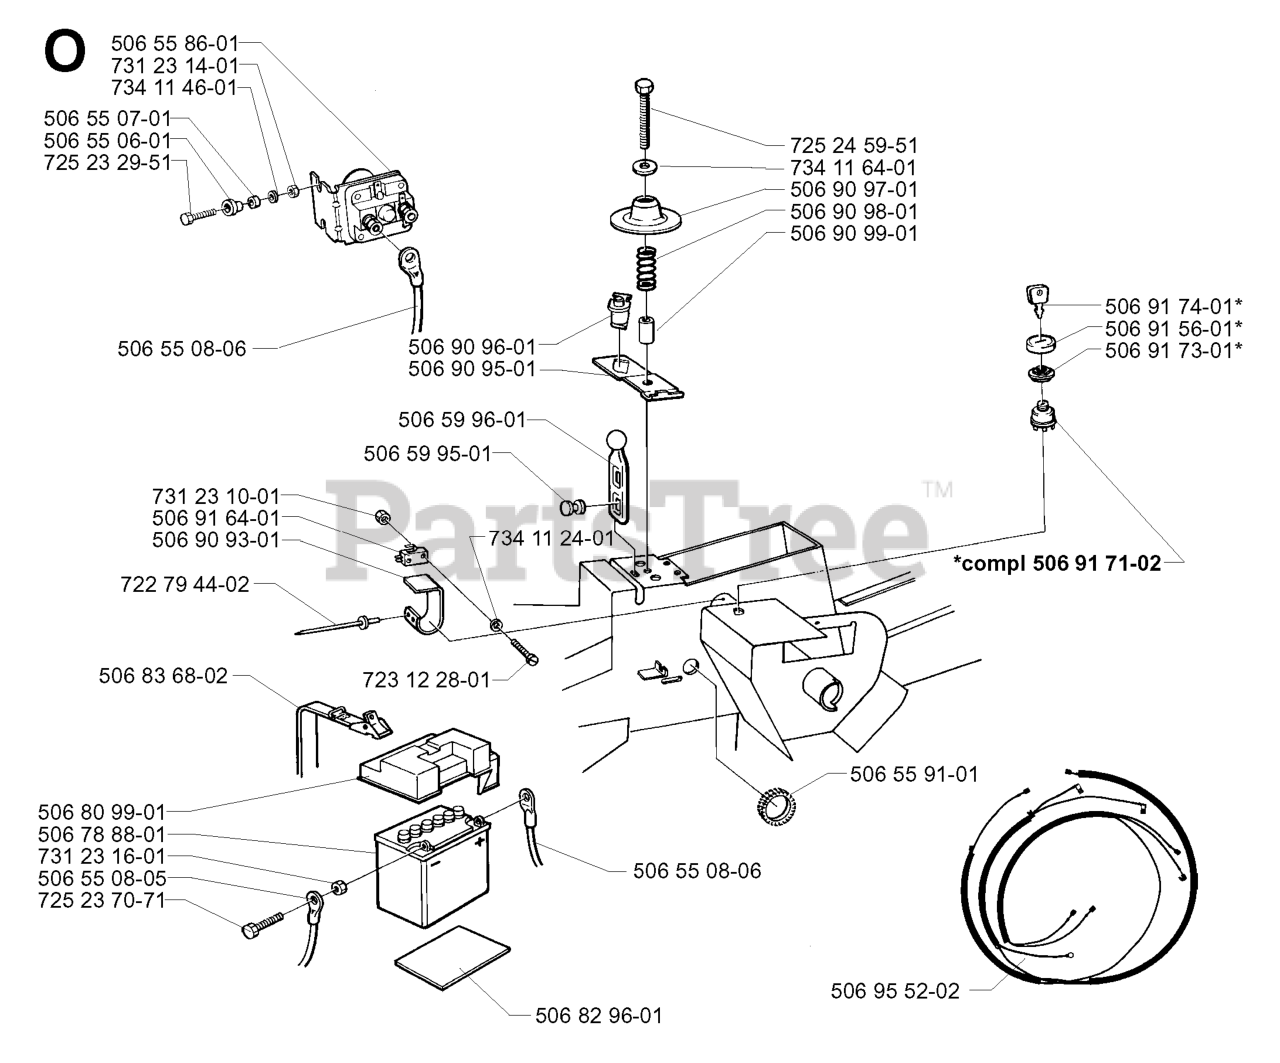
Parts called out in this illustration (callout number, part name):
1	DECK W/DECALS 61" HUS
2	SPINDLE ASSY - 52/61"
3	RP PULLEY - 61"
4	BLADE OEM 21" (61" DECK)
5	NUT 5/16C CENTERLOCK
6	ANTI-SCALP ROLLER
8	WASHER 3/8 FLAT
9	NUT 3/8C CENTERBLOCK
10	DECK BELT 61
11	HCS 3/8C X 3 1/2
12	HCS 5/16C X 1 1/4
13	DISCHARGE CHUTE
14	BELT SHIELD 61" RIGHT
15	SPINDLE WASHER
16	ZERK
17	HCS 5/16C X 3/4
18	DECK SPRING
19	IDLER PULLEY
20	IDLER PULLEY (TALL)
21	IDLER BUSHING
22	NUT 7/16C CENTERLOCK
23	HCS 3/8C X 2 1/2
24	NUT 7/16C WHIZ
25	HCS 5/8F X 1 1/4
26	LOCKWASHER 5/8
27	WASHER 7/16 LOCK
28	DRILLED BOLT 7/16-20 X 1 1/2"
31	KNOB, THREE PRONG
32	SUPPORT PLATE
33	4CS 3/8C X 1 SERRATED HEAD
34	NUT 1/2-13 HEX NYLOC ZD
35	WASHER 1/2 FLAT
36	ZERK
38	PIVOT BUSHING
39	WASHER, SUPPORT
40	HCS 1/2C X 3 1/4
41	SHAFT SEAL
43	52/61 SPINDLE - SPLINED SHAFT
44	BOTTOM DUST CAP
45	TOP DUST CAP
46	PLUG-VENTED
47	WASHER 5/16 FLAT
48	HCS 7/16C X 1 1/2
49	LIFT CHAIN
51	CENTER BAFFLE - 61
52	MAIN BAFFLE - 61" BLK
53	CARRIAGE BOLT 5/16C X 5/8"
